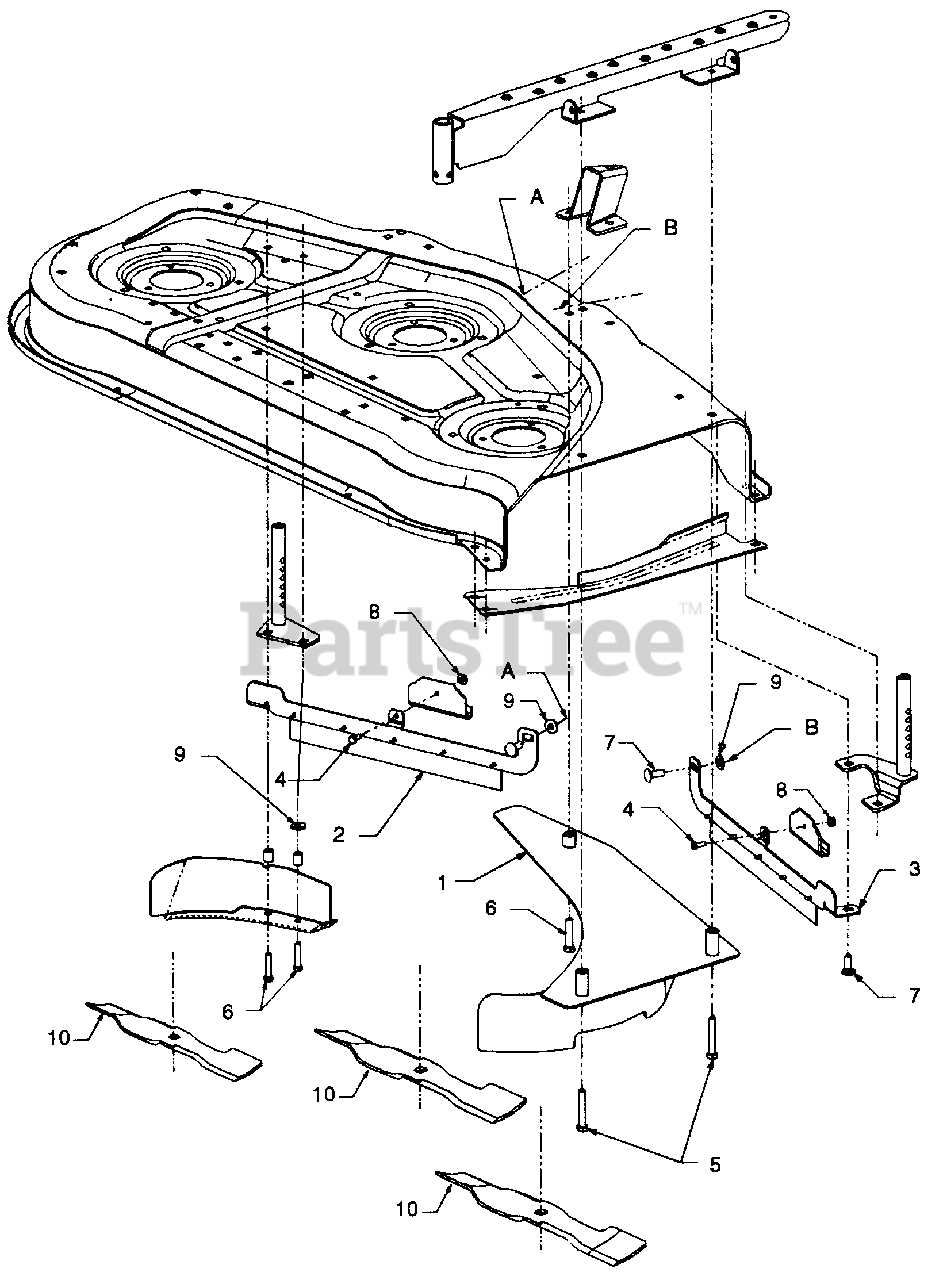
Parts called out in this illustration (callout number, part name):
4	Screw, Hex Cap, 1/4-20 X .62 GR5
5	Screw, Hex Cap, 3/8-16 X 2-1/4 GR5
6	Screw, Hex Cap, 3/8-16 X 1-3/4 GR5
7	Bolt, Carriage, 3/8-16 X 1.0 GR5
8	Nut, Hex Flange Lock, 1/4-20
9	Washer, Flat, .406 X 1.0 X .105
10	Blade, Mulching, 16.5 Lg
